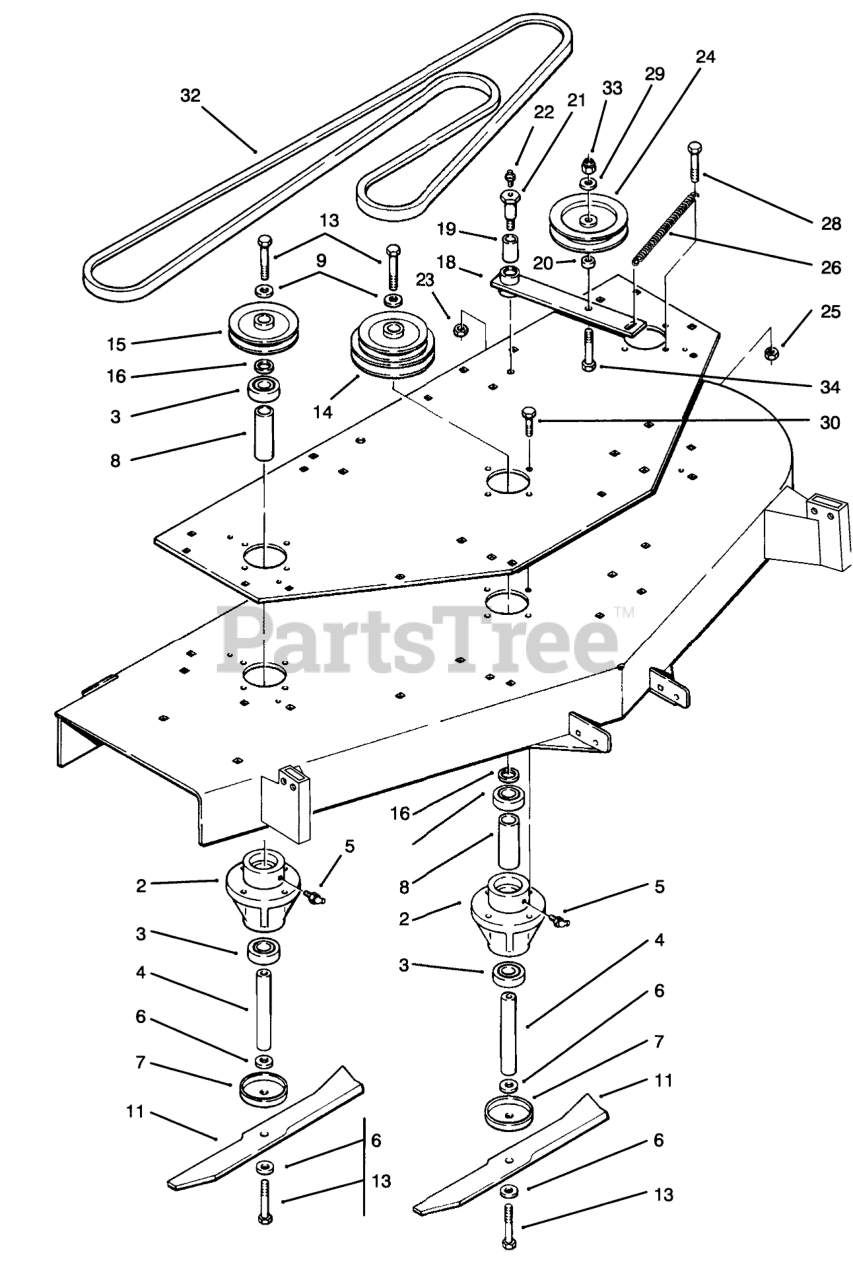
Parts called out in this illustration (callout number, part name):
1	S/A COMM MWR SPINDLE
2	HOUSING-SPINDLE
3	BEARING-BALL
4	SHAFT-SPINDLE
5	FITTING-GREASE
6	WASHER-SPECIAL
7	CUP-SPINDLE
9	WASHER-SPECIAL
11	BLADE
13	Bolt
14	Pulley-Center Spindle
15	PULLEY-OUTER
16	SPACER
18	Idler Arm Assembly (Incl. Ref. #19)
19	BUSHING
20	SPACER
21	BOLT-SHOULDER
22	FITTING-GREASE, 90 DEG
23	NUT-LOCK, NI
24	PULLEY-IDLER
25	NUT-JAM
26	SPRING-EXTENSION
28	SCREW-HH
29	WASHER-FLAT
30	SCREW-HH, LOCK
32	BELT-V
33	NUT-LOCK, NI
34	SCREW-HH
